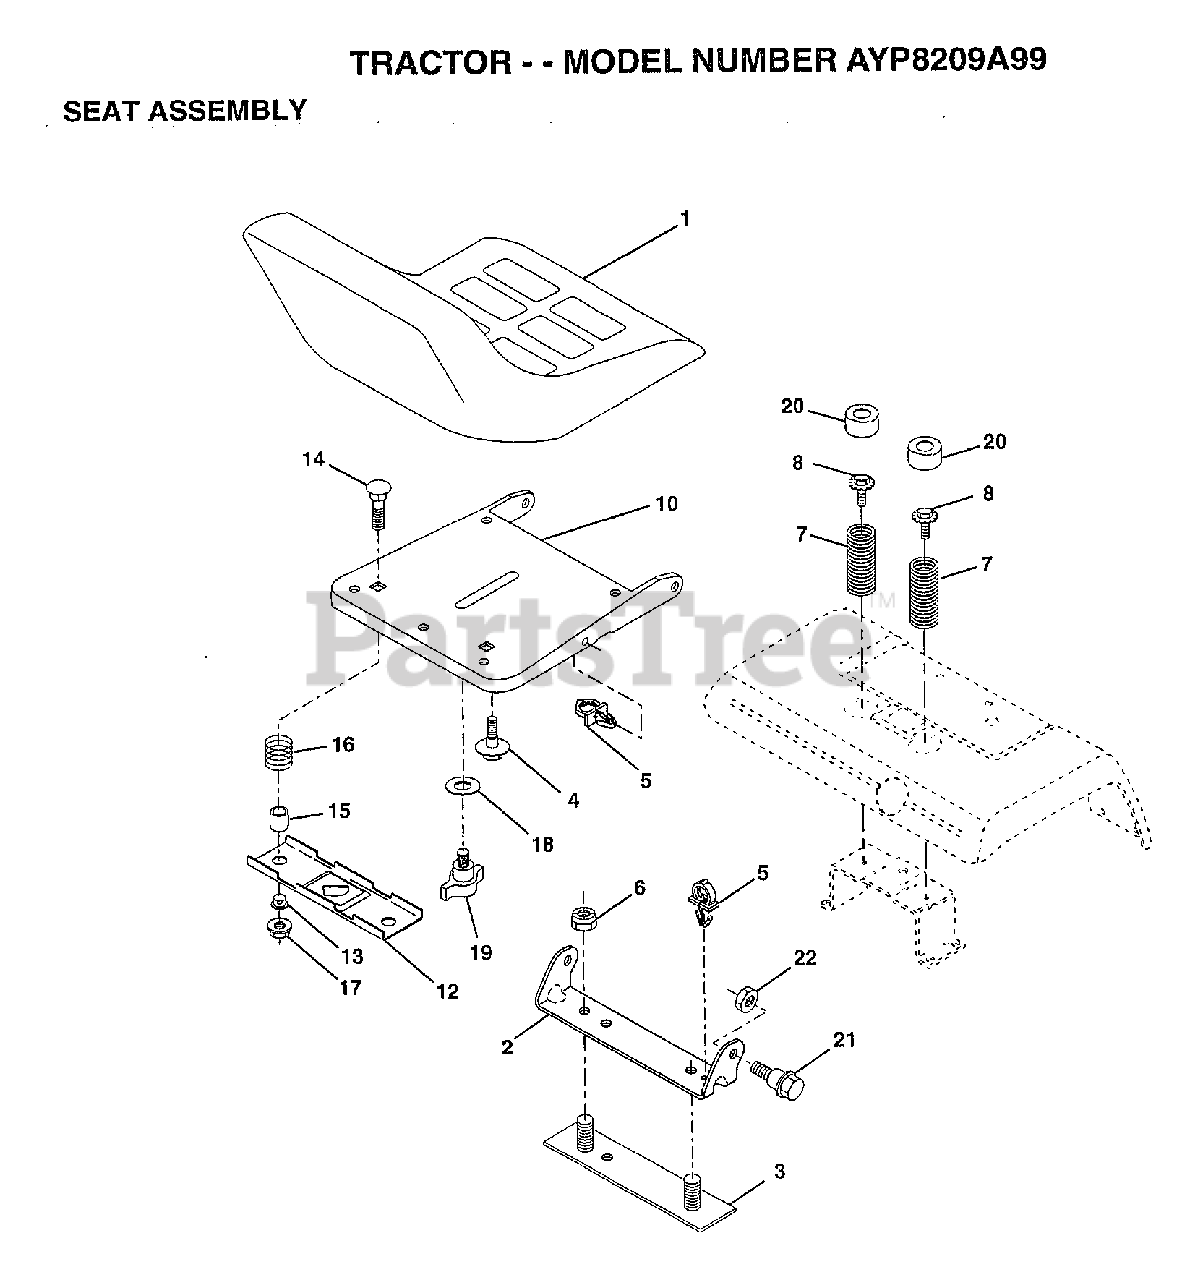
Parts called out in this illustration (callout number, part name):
2	BRACKET PVT SEAT
3	STRAP ASM FENDER
4	"BOLT,SHOULDER"
5	CLIP.PUSH-IN.HING
6	NUT
7	SPRING COMPRESSIO
8	BOLT.5/16-18.UNC
10	PAN-SEAT
12	BRKT SWITCH
13	BUSHING
14	BOLT-RD HD SQ NK
15	SPACER SPLIT
16	SPRING COMPRESSED
18	WASHER
19	KNOB.SEAT.ADJ.WINGNUT
20	CAP SPRING
21	"BOLT,SHOULDER"
